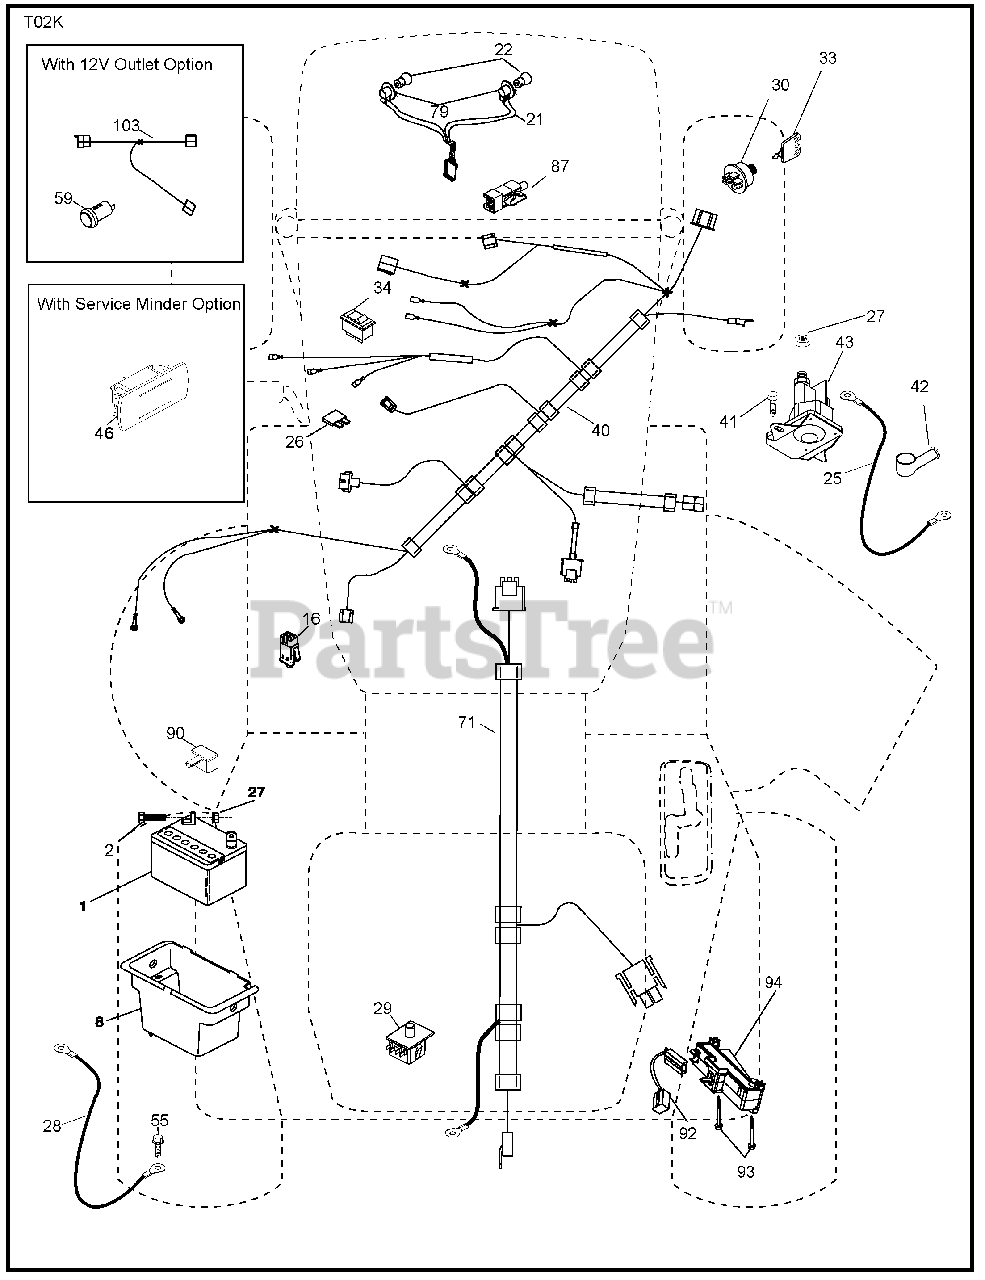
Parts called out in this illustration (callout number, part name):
1	Battery
2	Bolt Hex Head 1/4-20 x 3/4
8	Box Battery
16	Switch Interlock Push-In
21	Harness Socket Light w/4152J
22	Bulb Light
25	Cable Starter
27	Nut Keps Hex 1/4-20 unc
28	Cable, Ground Blk
29	Switch, Seat
30	Switch, Ign
34	Switch Light/Reset
40	Harness Ign. Dash
41	Screw Thd Cut 1/4-20 x 1/2
42	Cover, Terminal
43	Solenoid
55	Screw Thdrol 5/16-18 x 1/2 TYTT
71	Harness Ign.
79	Socket Asm. Bulb Twistlock
87	Switch Interlock Clutch
90	Cover Terminal
92	Harness Pigtail Reverse Switch
93	Screw Plastite 10-14 x 2.0
94	Module Reverse ROS
